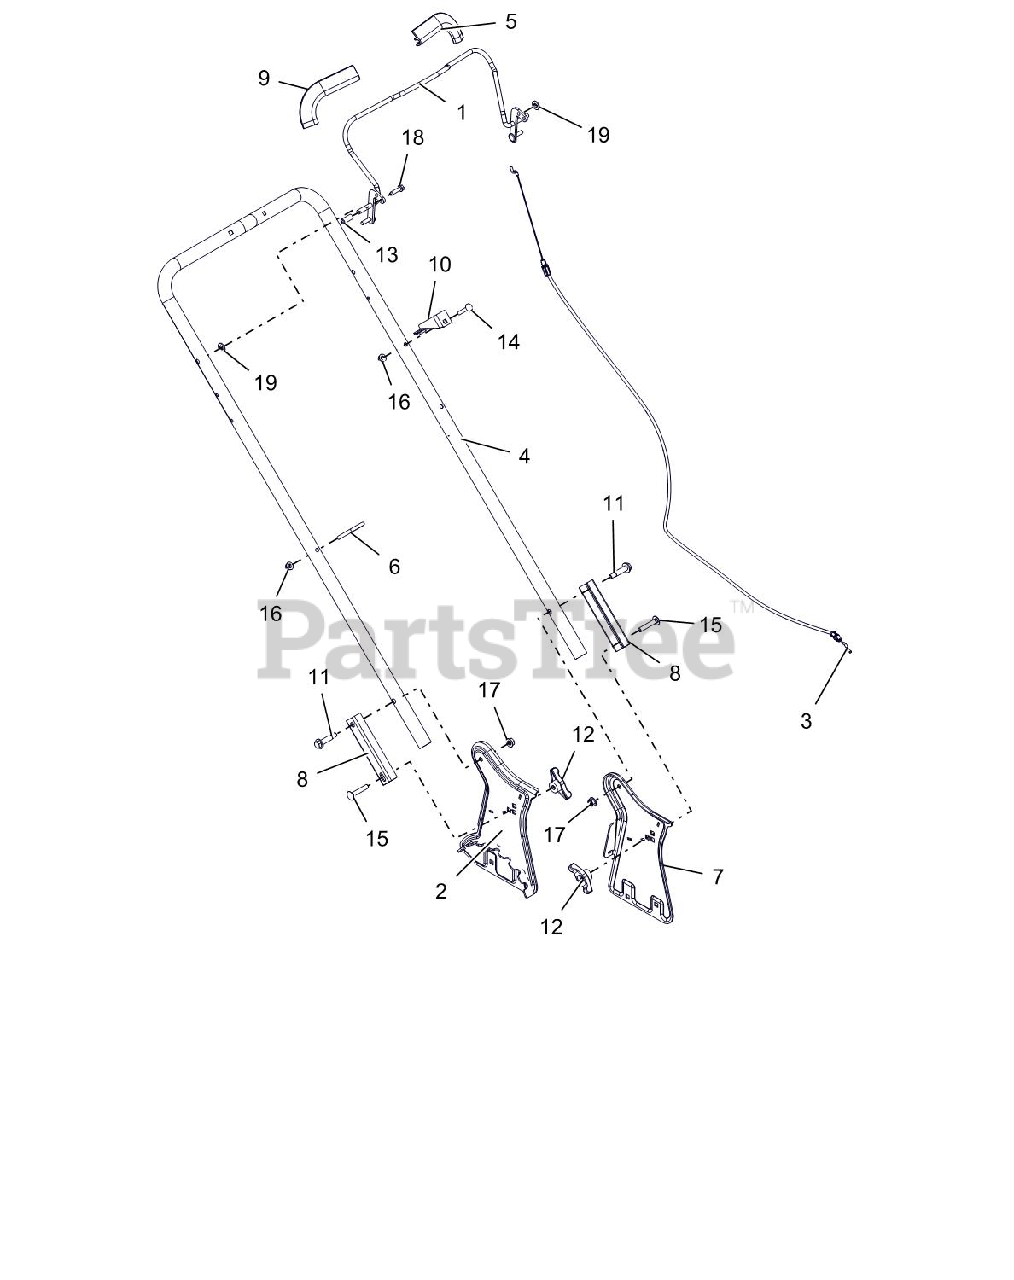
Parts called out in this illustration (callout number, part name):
1	WLDMT, OPC BAIL
2	SUPPORT, RH HANDLBAR
3	CABLE, OPC, RAZOR LM
4	HANDLEBAR, LM
5	GUARD, FINGER - LH
6	HOLDER, RECOIL CORD
7	SUPPORT, LH HANDLEBAR
8	BRKT, HANDLEBAR FIXED ADJUST
9	HAND GRIP W/ DECAL
10	BRKT, CABLE ANCHOR - LM PUSH
11	BLT-SHLDR, .50X1.15X.312-18GR5
12	KNOB,WING .31-18 UNC NYL/TALC
13	CAP, VINYL, .25 ID
14	@BLT-RDHDSQNK .25-20X1.50 G5YZ
15	@BLT-RDHDSQNK .31-18X1.75 G5YZ
16	@NUT-LK-TOP-FLG .25-20 YWZC
17	@NUT-LK-TOP-FLG .31-18 YWZC
18	@SCR-TAP .25-20X1.00 HWH TR YZ
19	@WSHR-FL-STL.344X.688X.065YWZC
